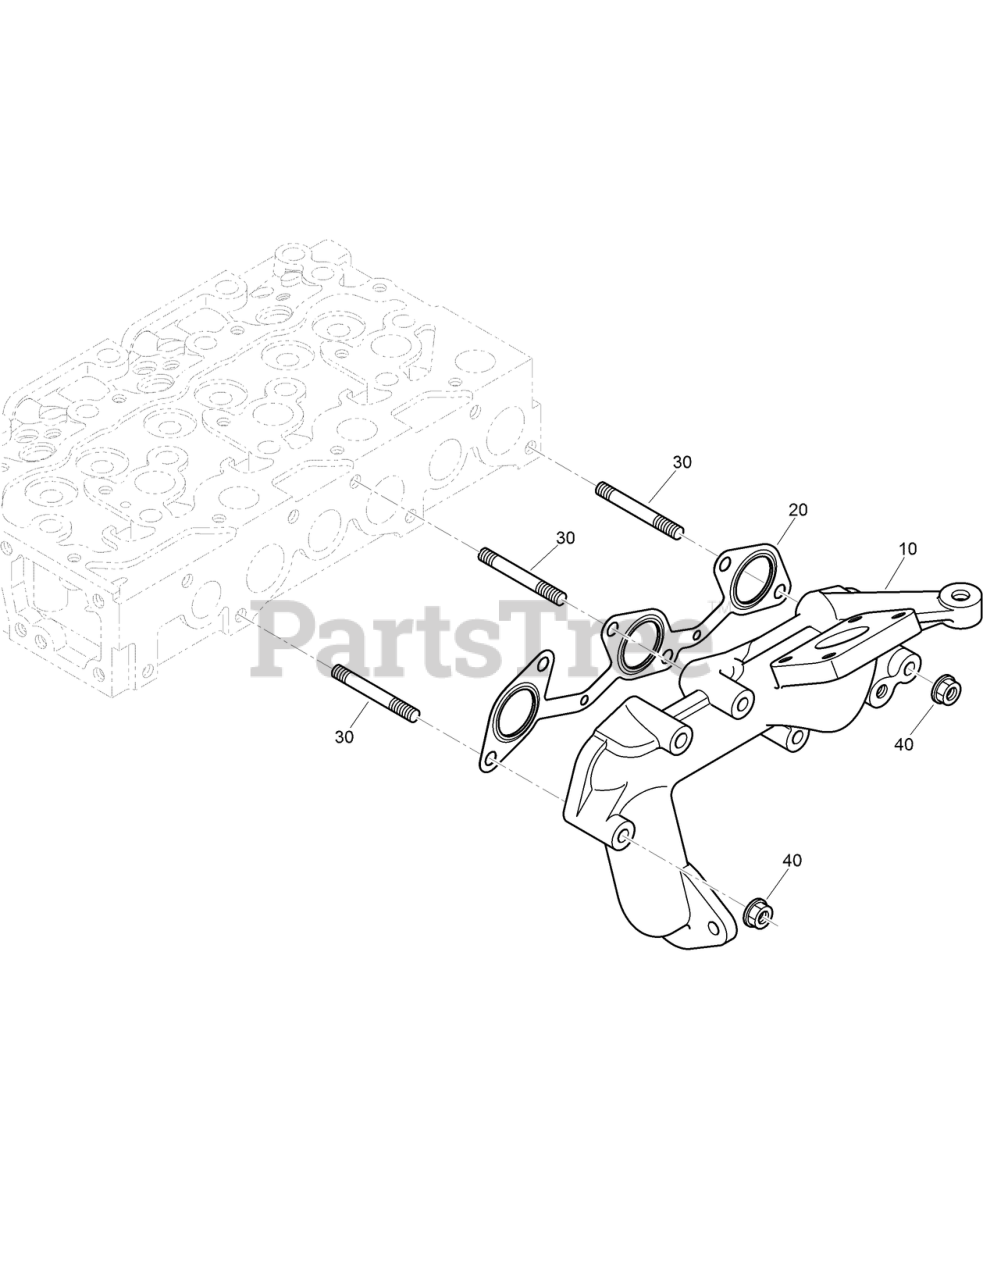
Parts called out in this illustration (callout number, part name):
10	MANIFOLD-EXHAUST
20	GASKET-MANIFOLD, EXHAUST
40	NUT-FLANGE
